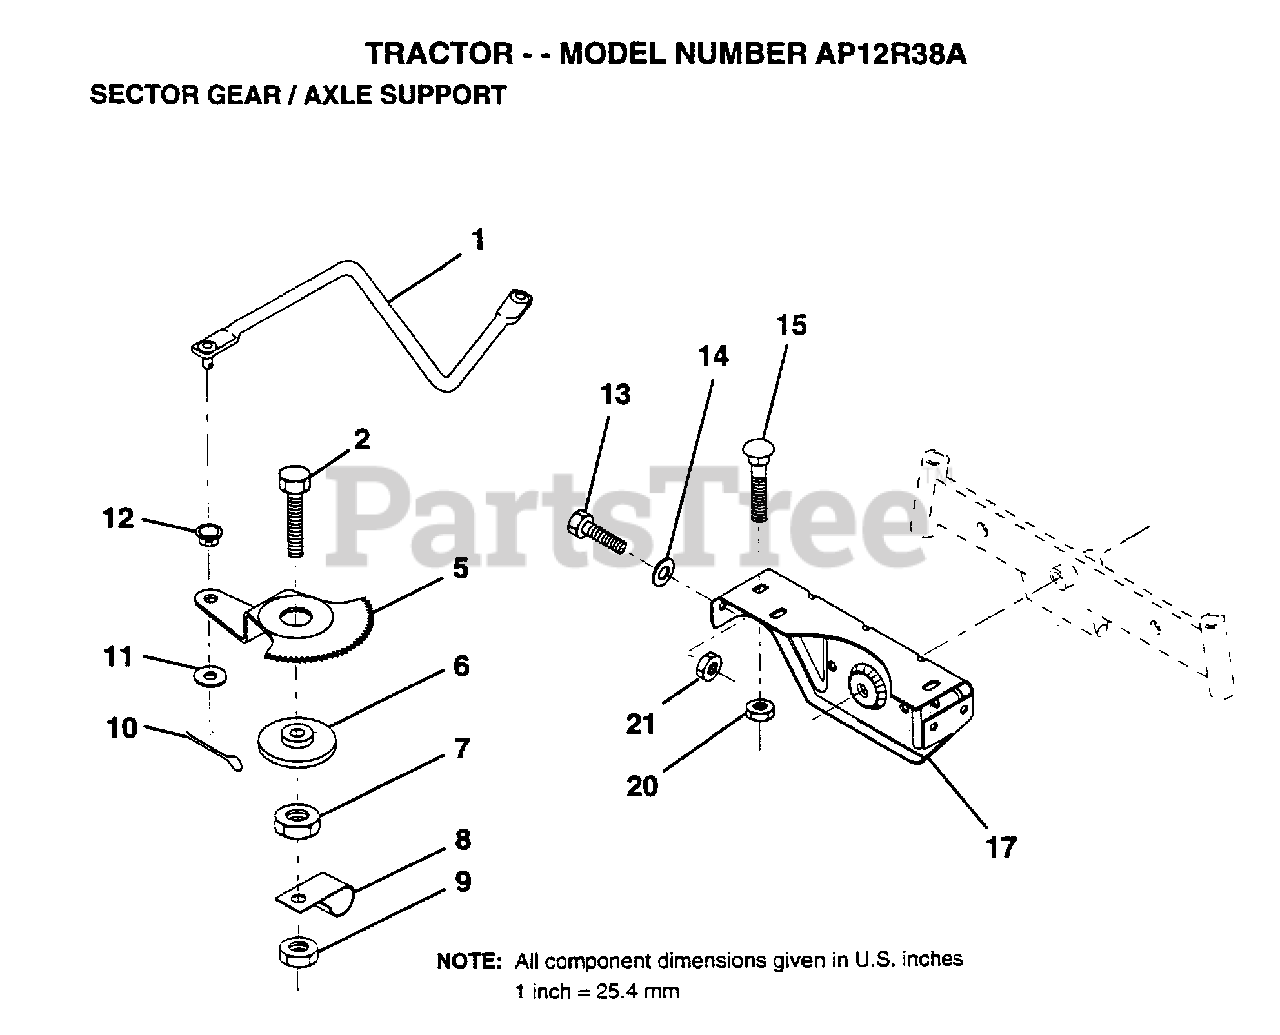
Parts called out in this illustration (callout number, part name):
1	DRAG LINK
2	"BOLT,HEX"
5	GEAR SECTOR
6	BUSHING
7	NUT
8	CLIP INSULATOR
9	NUT LTV
10	COTTER PIN
11	WASHER
12	BUSHING.DRAGLINK
13	BOLT
14	WASHER
15	BOLT
17	SUPT AXLE FRONT
20	NUT
